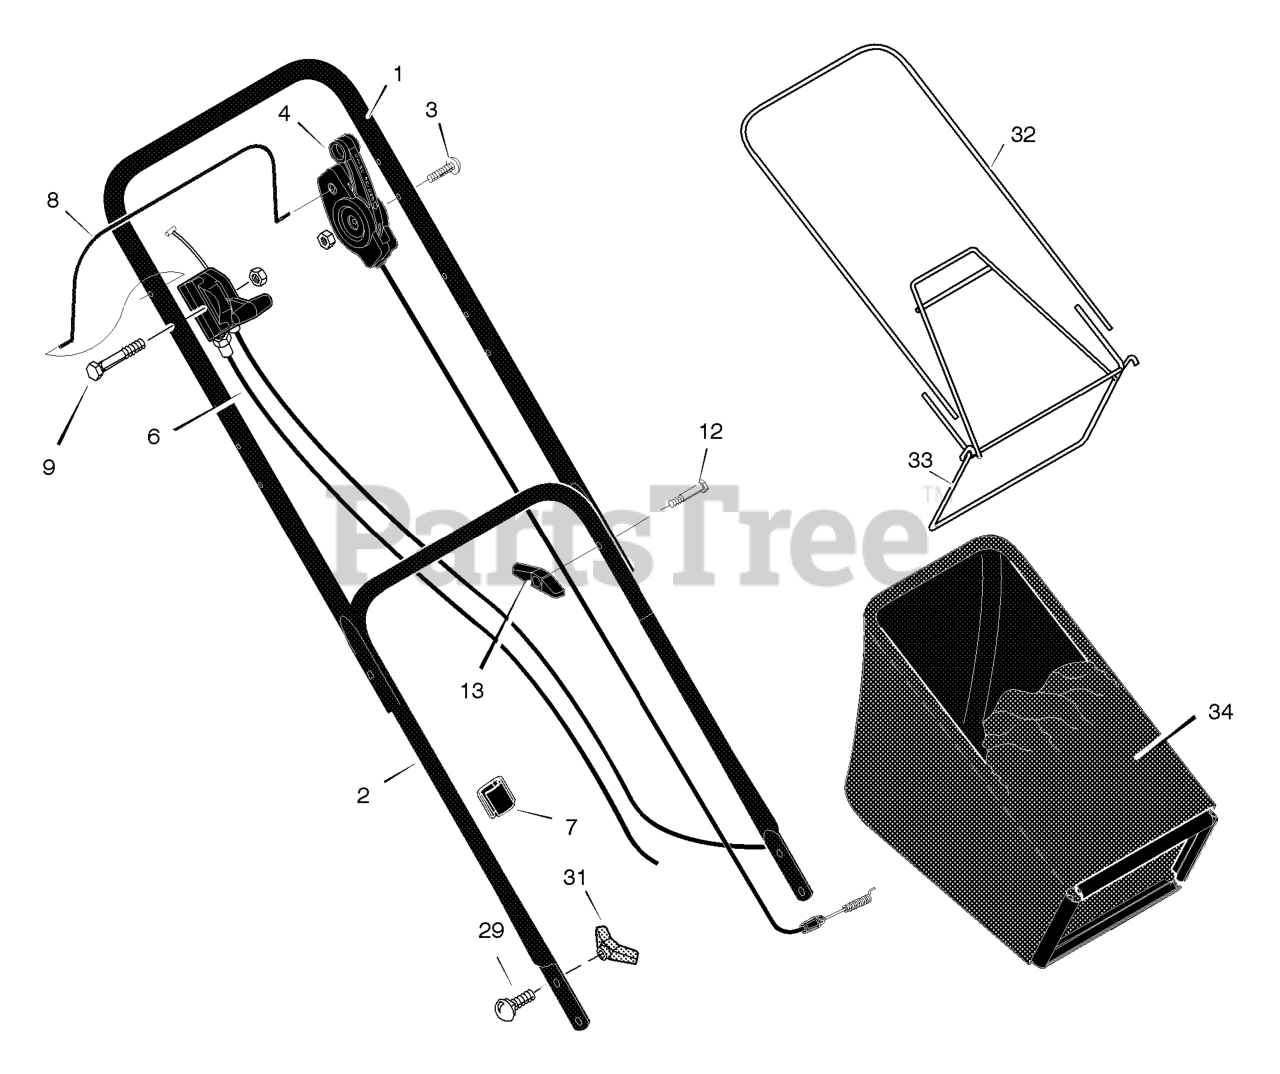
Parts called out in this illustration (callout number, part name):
1	Handle, Upper (Black)
2	Handle, Lower (Black)
4	Control, Drive
5	Locknut
6	Cable, Stop
7	Fastener, Cable
8	Lever, Stop
11	Control, Throttle
13	Knob
16	Guide, Rope
29	Bolt, Carriage
31	Knob, Plastic
32	Tube, Bag
33	Frame Assembly
34	Bag, Cloth
